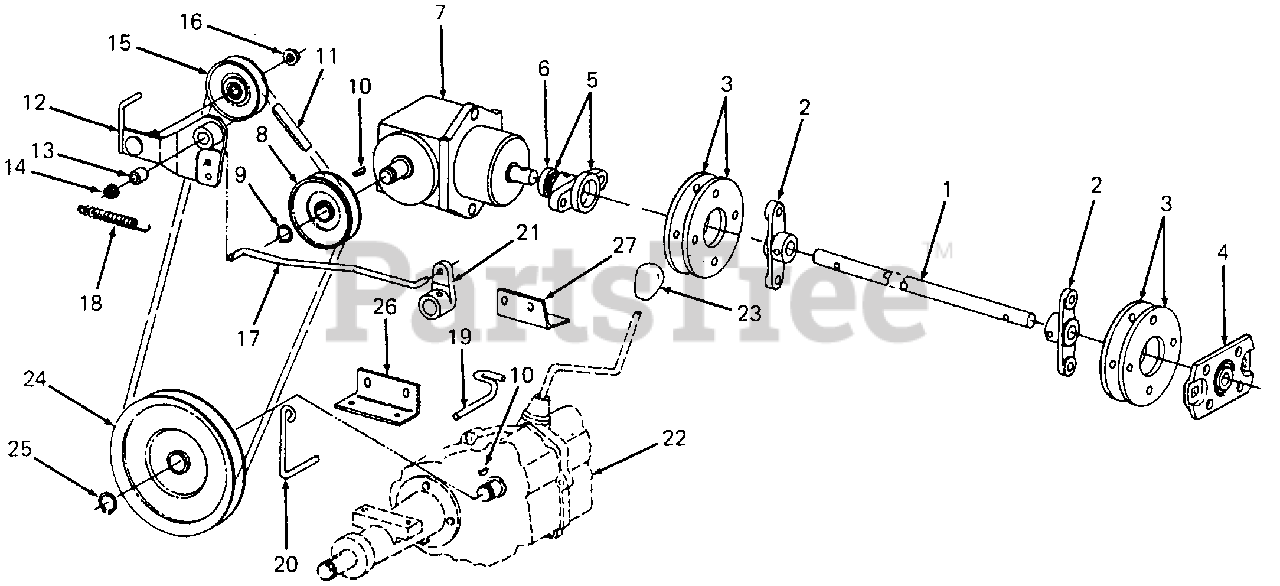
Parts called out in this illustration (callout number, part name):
1	Shaft, Drive
2	Arm, Coupling
3	Disc, Flexible Coupling
4	Flange Assy, Drive Shaft
5	Coupler Assy
6	Bushing, Ball
7	Gear Box, Right Angle
8	Pulley, Drive 4L, 3.25 OD
9	Ring, Snap, .625 Dia
10	Key, Woodruff #9, 3/16 X 3/4
11	V-Belt
12	Arm Assy, Clutch
13	Bushing, Clutch Arm
14	Nut, Hex Flange Lock, 5/16-18
15	Pulley, Drive-Idler
16	Nut, Hex Flange Lock, 3/8-16
17	Rod, Clutch
18	Spring, Extension
19	Guide, Belt
20	Guide, Belt
21	Lever, Neutral Return
22	Transaxle
23	Knob, Shifter
24	V-Pulley 4L, 6.25 OD
25	Ring, Snap, .75 Dia
26	Bracket, Transmission Mounting, RH
27	Bracket, Transmission Mounting, LH
